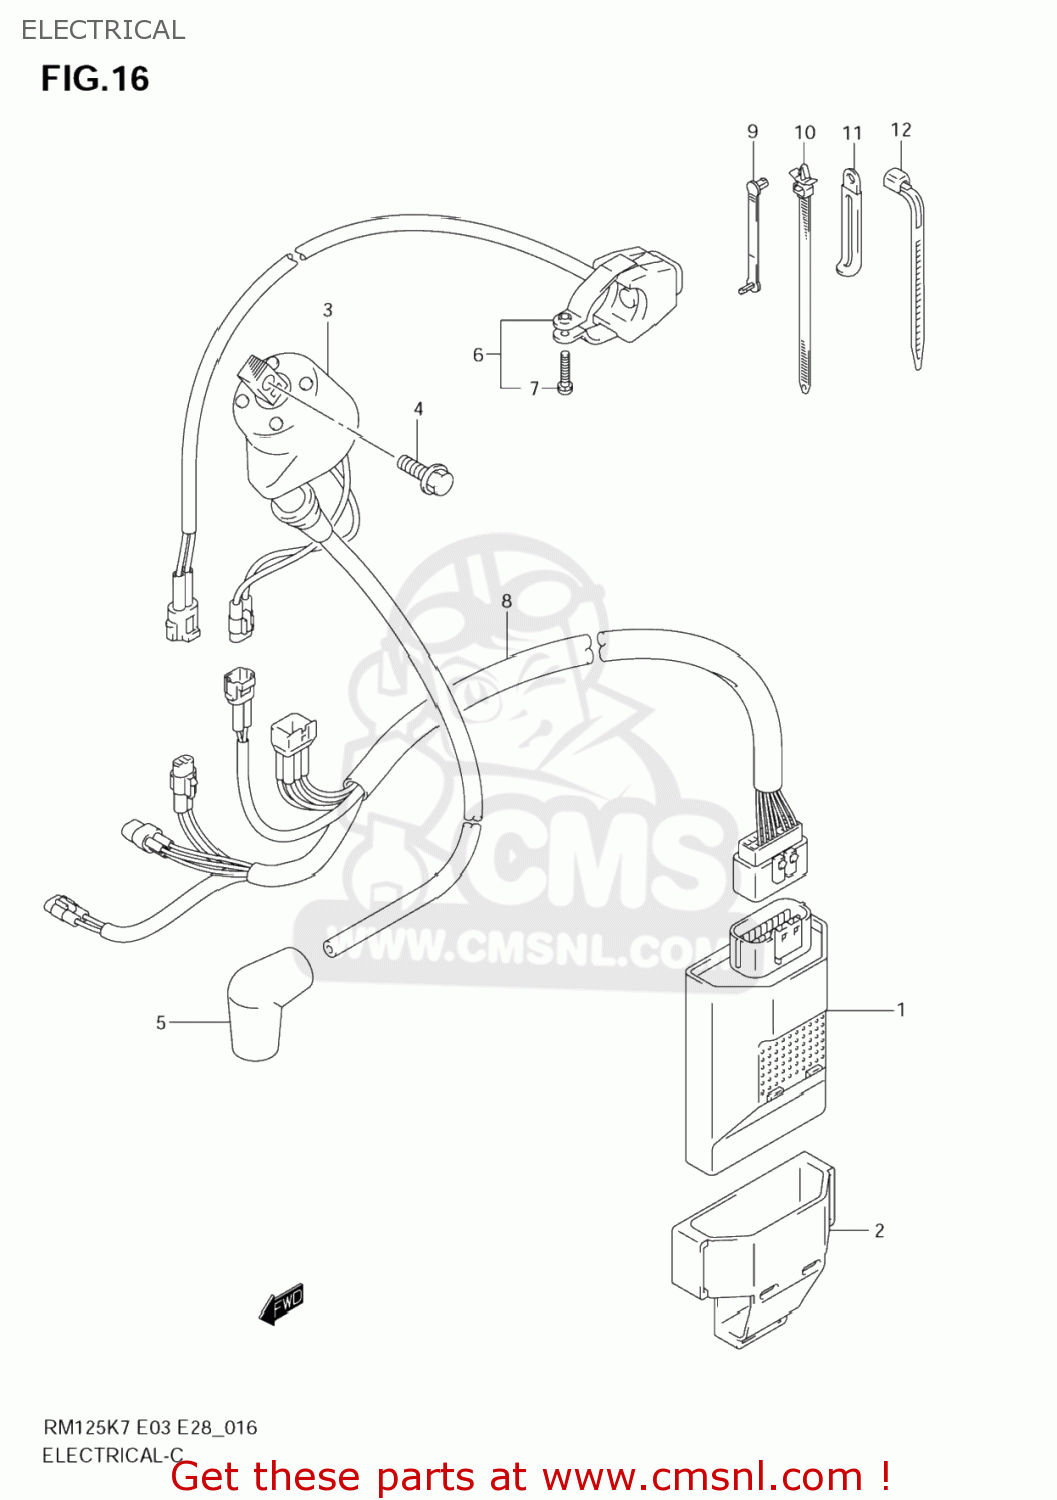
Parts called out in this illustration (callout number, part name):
1	CDI UNIT
2	CUSHION,CDI UNIT
3	COIL ASSY,IGNITION
4	BOLT(6X16)
5	CAP,SPARK PLUG
6	SWITCH ASSY,ENGINE STOP
7	SCREW
8	HARNESS,WIRING
9	CLAMP(L:63)
10	CLAMP(L:90)
11	CLAMP(L:45)
12	CLAMP(L:95)
